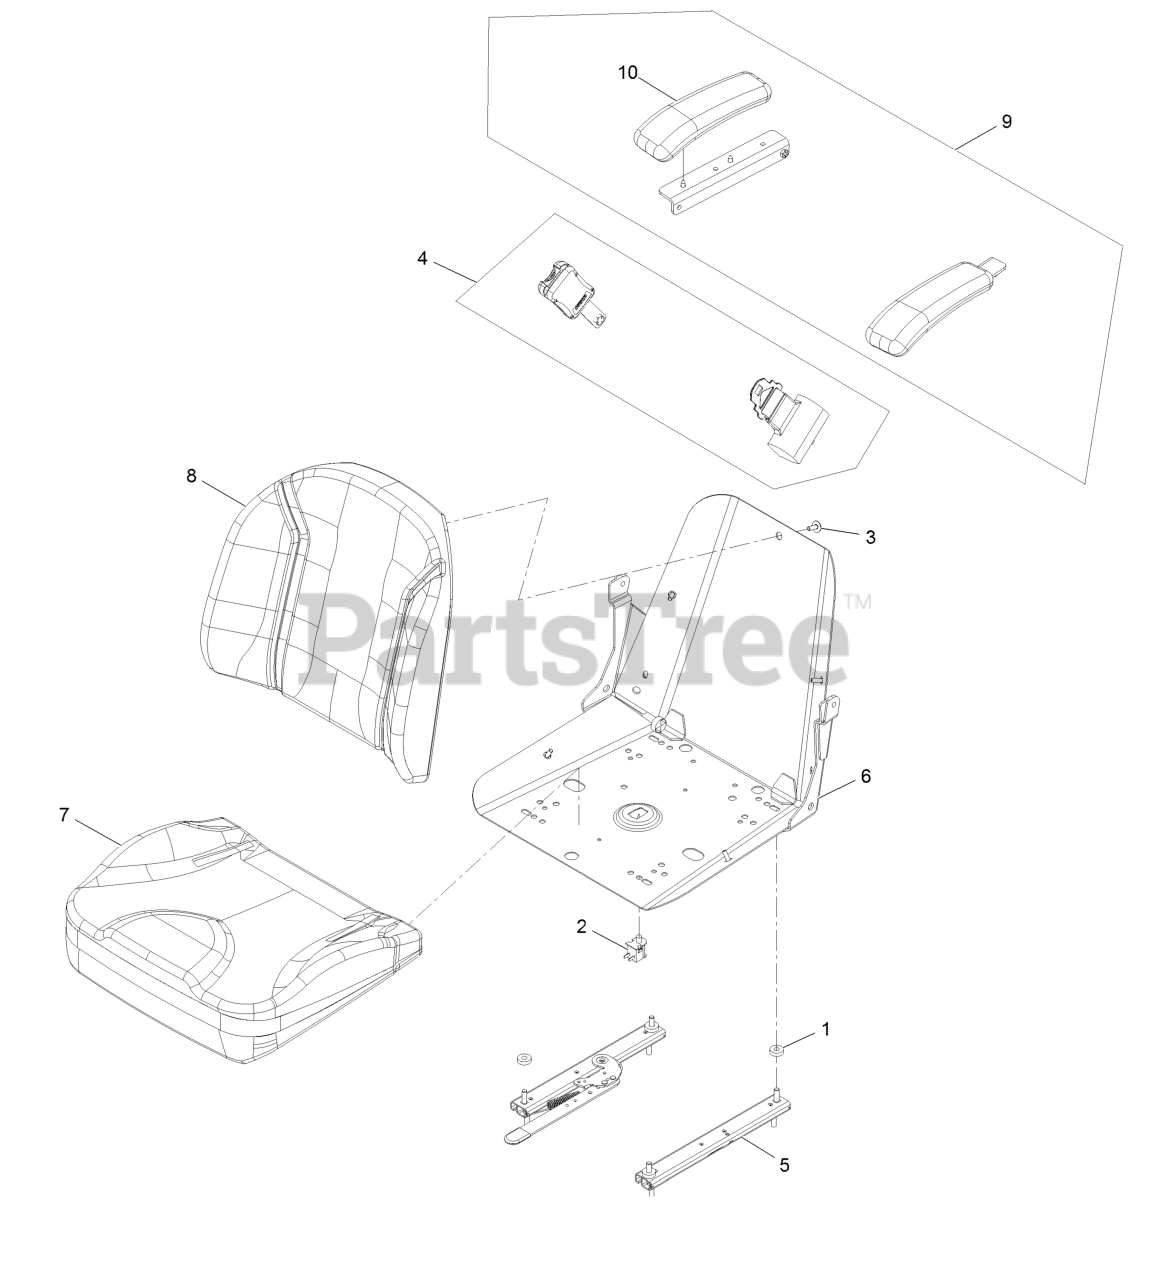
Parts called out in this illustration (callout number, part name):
1	Spacer-Pin, Mounting
3	Screw-HWH 1/4-20 X 3/4 Taptite
4	Kit-Seat Belt
5	ASM-Seat Track Svc
6	Frame-Seat Svc
7	Cover-Seat Bottom Svc
8	Cushion-Seat, Back
9	Armrest Kit
10	Cushion-Rest, Arm
